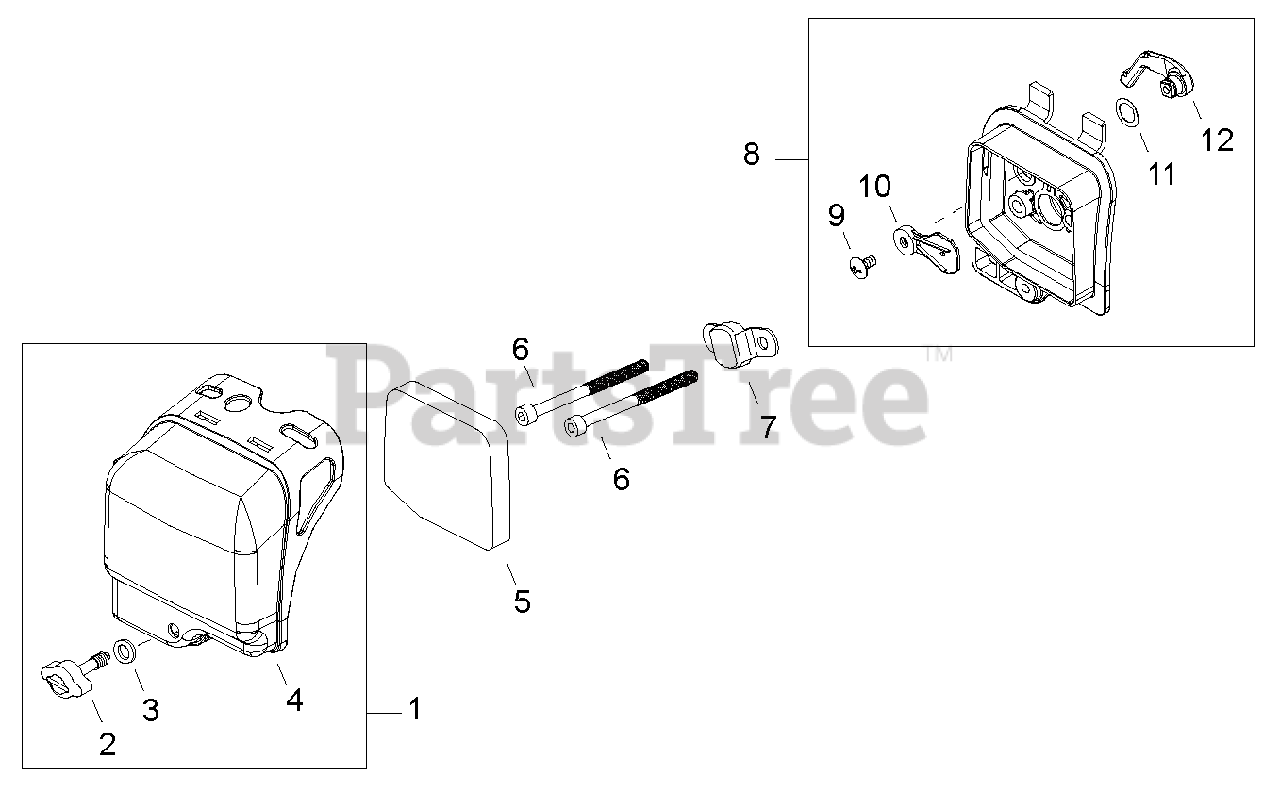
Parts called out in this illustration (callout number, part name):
2	THUMBSCREW
3	WASHER - VYNYL
4	COVER, AIR FILTER
5	FILTER, AIR
6	SCREW - 5X60
7	PLATE, PREVENT
8	AIR FILTER CASE ASSY
8-1	AIR FILTER COVER ASSY
9	SCREW - 4X12
10	PLATE, CHOKE
11	WASHER - WAVE
12	LEVER, CHOKE
